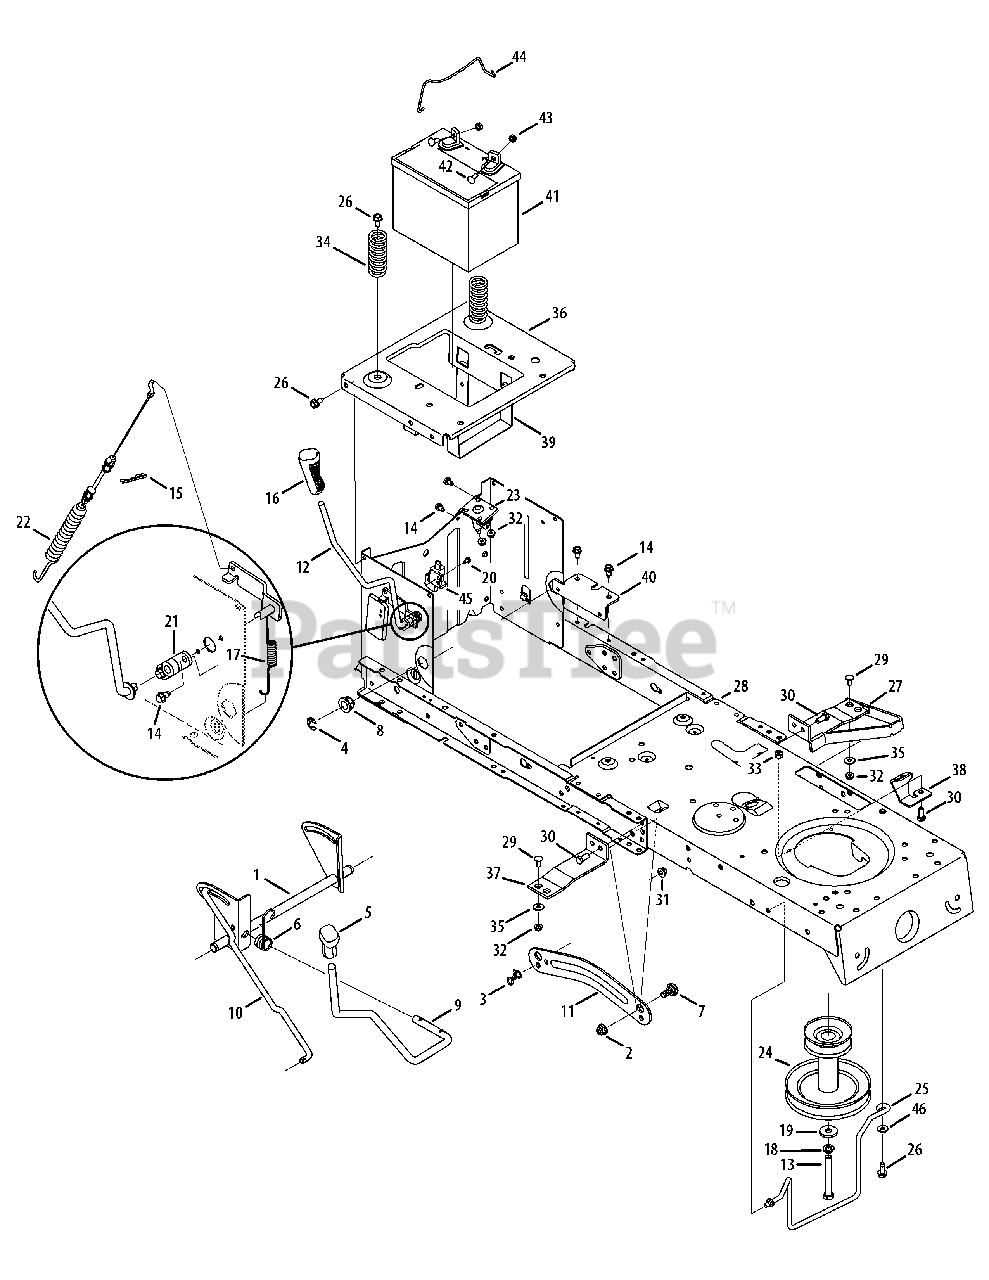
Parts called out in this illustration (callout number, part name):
1	Shaft, Lift
2	Nut, Hex Flange Insert Lock, 3/8-16
3	Bow-Tie Pin, RH
4	E-ring, .625 Shaft
5	Grip, Handle
6	Spring, Lift Handle Torsion
7	Bolt, Shoulder, .625 x .175:3/8-16
8	Bearing, Hex Flange,
9	Handle, Lift
10	Lift Rod, 13.68
11	Arm, Deck Lift RH
11	Arm, Deck Lift LH
12	PTO Handle Assembly
13	Screw, Hx. Hd., 7/16-20 x 3.25
14	Screw, Hd. Tapp, 1/4-20 x .5
15	Click Pin
16	Handle Grip
17	PTO Spring, Extension
18	Washer, Flat, 7/16
19	Washer, Flat, .450 x .250 x .164
20	Shoulder Screw, #10-32 x .500
21	PTO Bearing
22	Deck Engagement Cable
23	12v. Solenoid
24	Engagement Pulley
25	Belt Keeper Rod Assembly
26	Screw, Hd. Tapp, 5/16-18 x .75
27	Support Bracket Assembly
28	Rider Frame Assembly
29	Carriage Screw, 1/4-20 x .62
30	Screw, Hx. Hd., 5/16-18 x .75
31	Nut, Hex Flange Insert Lock, 5/16-18
32	Nut, Hex Flange Insert Lock, 1/4-20
33	Hexlock Nut, 5/16-18
34	Spring, Compress., 1.28 x 3.125
35	Flat Washer, .28 x .74 x .063
36	Seat Bracket Frame
37	Running Board Bracket
38	Frame Support Bracket
39	Battery Bracket
40	Frame Brace Bracket
41	DieHard® Battery
42	Screw, Shoulder, .250 x .150
43	Nut, Sems, 1/4-20
44	Battery Rod
45	Interlock Switch
46	Flat Washer, .406 x .875 x .059
